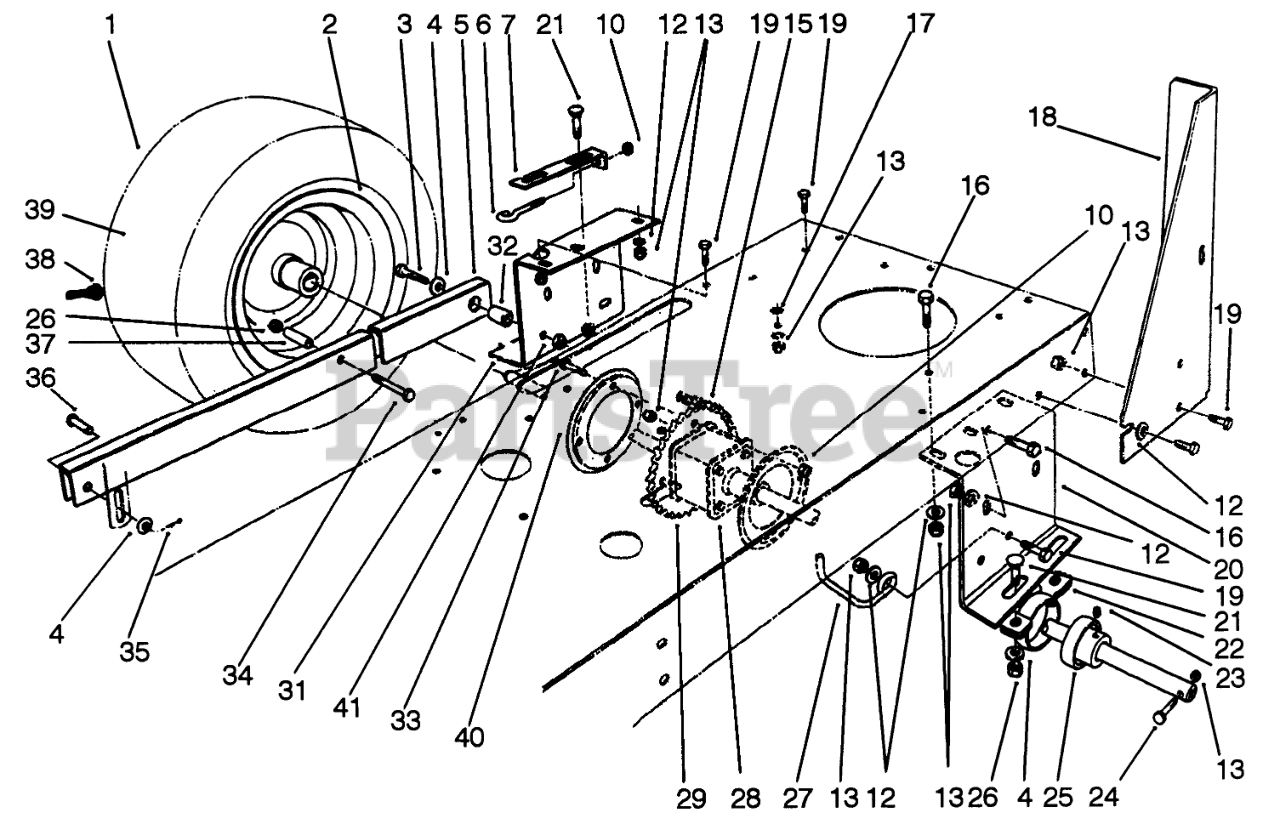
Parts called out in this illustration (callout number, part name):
3	SCREW-HH
4	WASHER-FLAT
5	Arm-Suspension R.H.
6	SCREW-ADJUSTING
7	PLATE-ADJUSTING
10	NUT-HEX
12	WASHER-PLAIN
13	NUT-LOCK, NI
15	ROLLER CHAIN
16	SCREW-HH
17	WASHER-LOCK, INTERNAL
18	LH STANDBAR B
19	SCREW-HH
20	LH REAR AXLE SUPT R
21	BOLT-CARR
22	RTNR-PILLOW BLK
23	SCREW-SET, HSH
24	AXLE MTG BOLT
25	Bearing-Ball (Incl. Ref. #23)
26	NUT-LOCK, NI
27	BELT GUIDE
28	DIFFERENTIAL
29	SPROCKET
31	RH AXLE SUPPORT R
32	PIN-SUPT ARM
33	SCREW-HH
34	SCREW-HH
35	PIN-COTTER
36	PIN-CLEVIS
37	SPACER-SPLIT TUBE
38	STEM-VALVE
39	TUBE-INNER
40	Guide-Chain
41	NUT-LOCK, NI
